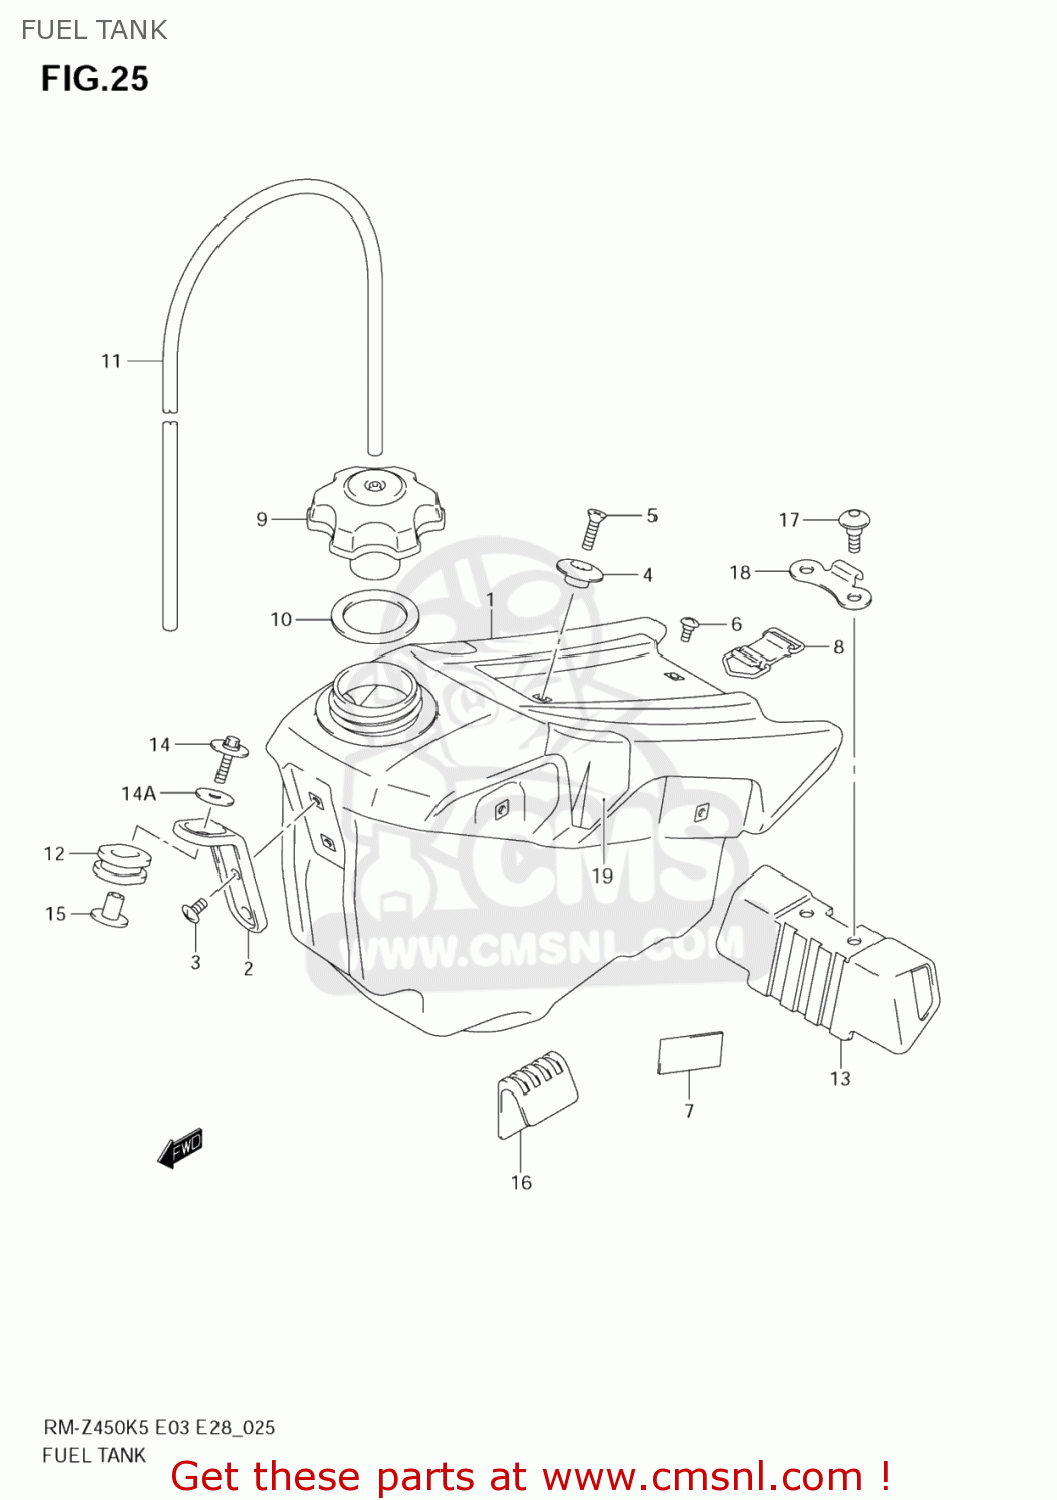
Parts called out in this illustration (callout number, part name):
1	TANK,FUEL(YELLOW)
2	BRACKET,FUEL T
3	SCREW 6X12
4	HOOK,SEAT FR
5	SCREW
6	SCREW(6X13.5)
7	CUSHION,FUEL TANK
8	BAND,FUEL TANK RR
9	CAP,FUEL TANK FILLER
10	GASKET,CAP (NAS)
11	HOSE(5X8.2X600)
12	CUSHION,FUEL TANK
13	CUSHION,FUEL TANK RR
14	BOLT(6X25)
14A	WASHER,FUEL TANK FR
15	SPACER,FUEL TA
16	CUSHION,TANK SIDE
17	SCREW(6X16)
18	HOOK,FUEL TANK BAND
19	TAPE SET,FUEL TANK
